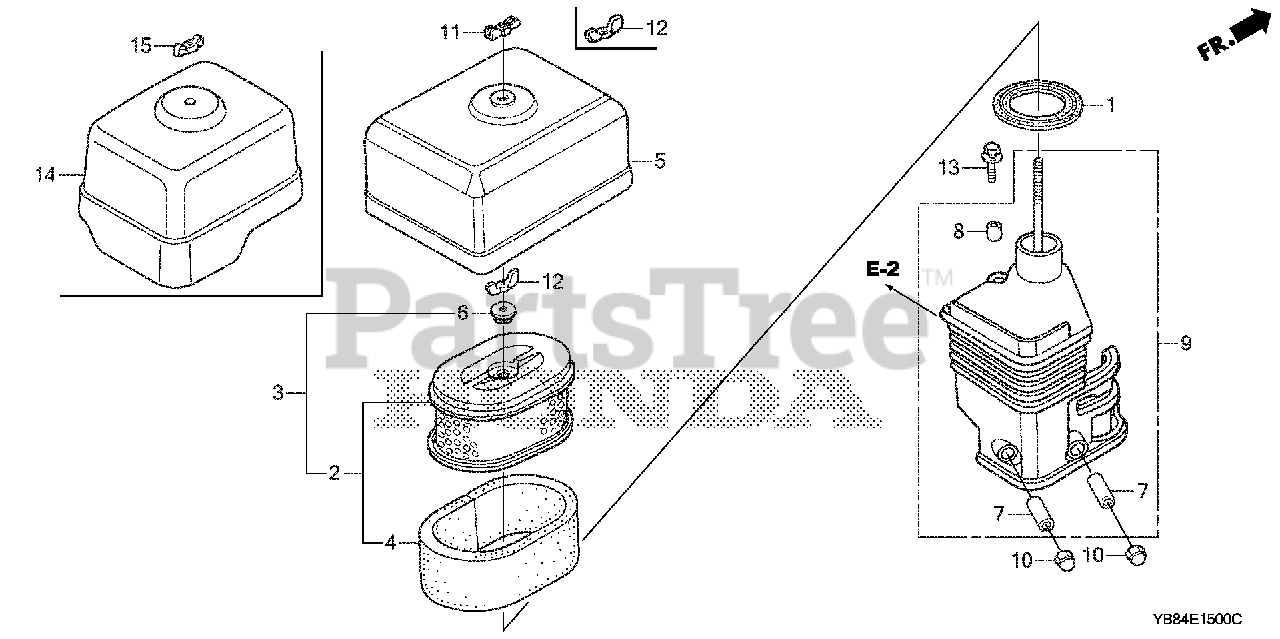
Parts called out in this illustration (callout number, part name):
1	GASKET, ELBOW
3	ELEMENT, AIR CLEANER (DUAL)
4	FILTER (OUTER)
6	GROMMET, AIR CLEANER
7	COLLAR, AIR CLEANER Use from Engine SN 1786085.
8	COLLAR B, AIR CLEANER
9	ELBOW, AIR CLEANER
10	NUT, FLANGE (6MM)
12	WINGNUT, TOOL BOX SETTING
13	BOLT, FLANGE (6X20)
14	COVER, AIR CLEANER
15	NUT, AIR CLEANER
